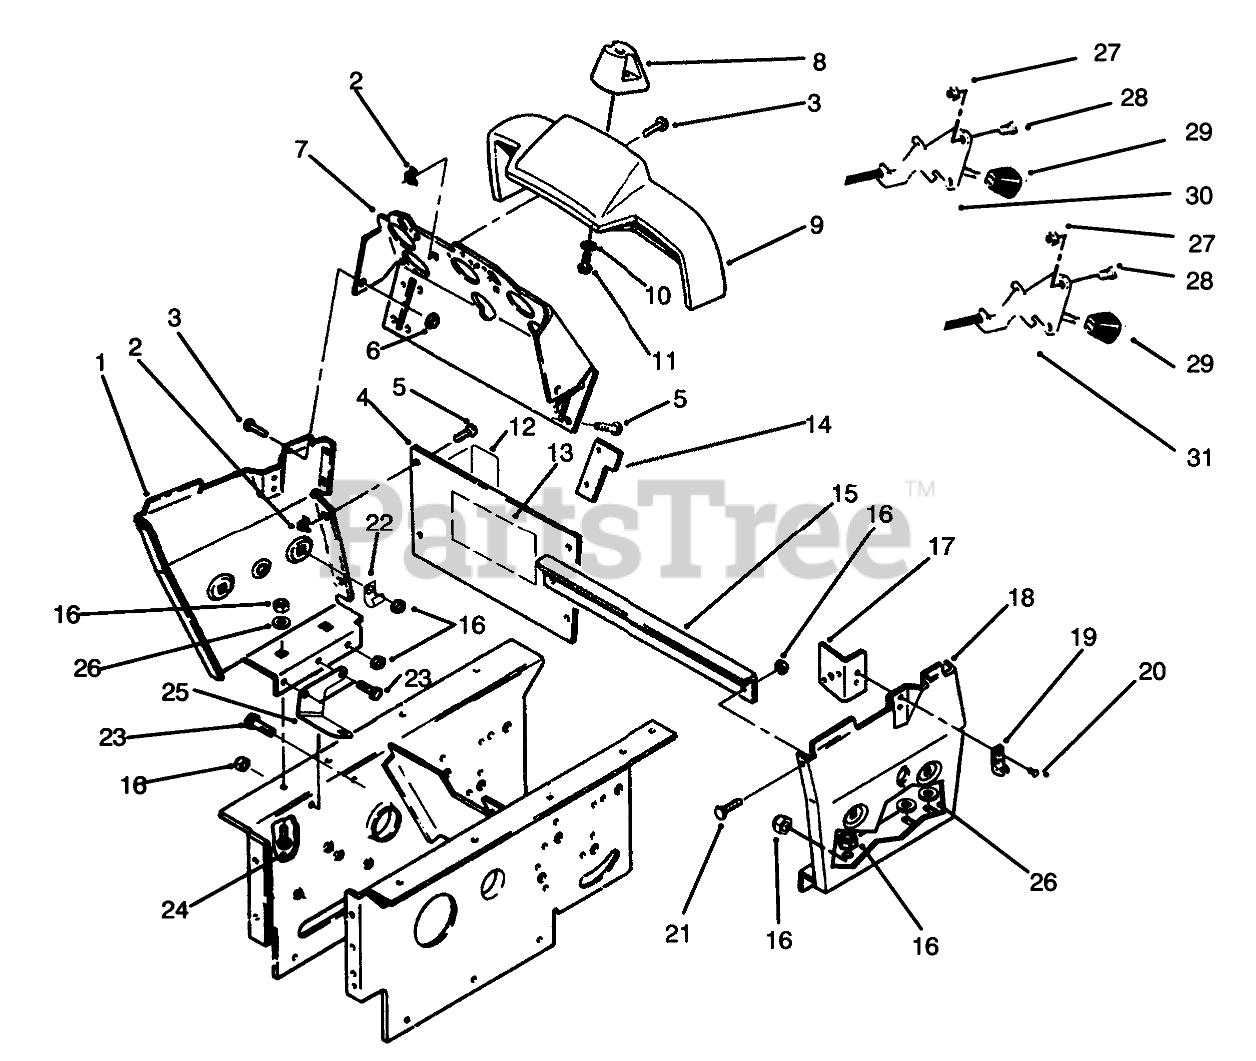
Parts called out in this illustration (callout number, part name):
1	Panel-RH
2	NUT-RETAINED
3	Screw
4	Plate-Hoodstand, Rear (Incl. Ref. #13)
5	Screw
6	NUT-HF
7	ASM-Panel
8	COVER-STEERING SHAFT
9	COVER-CONSOLE 5 GAGE
10	SWIVEL JACK
11	SCREW-#6 PLASTITE
12	DECAL PTO CLUTCH
13	DECAL - DANGER
14	STOP-CHOKE
15	STIFFENER-PANEL B
16	NUT-LOCK, NI
17	BRACKET-SWITCH SU
18	Panel-LH
19	KEEPER-LATCH
20	RIVET-POP
21	SCREW-HH
22	CLIP
23	SCREW-HH
24	CARRIAGE BOLT -4
25	Bracket-Control
26	WASHER-PLAIN
27	Nut
28	SCRW-PHC
30	CONTROL-THROTTLE
31	CONTROL-CHOKE
